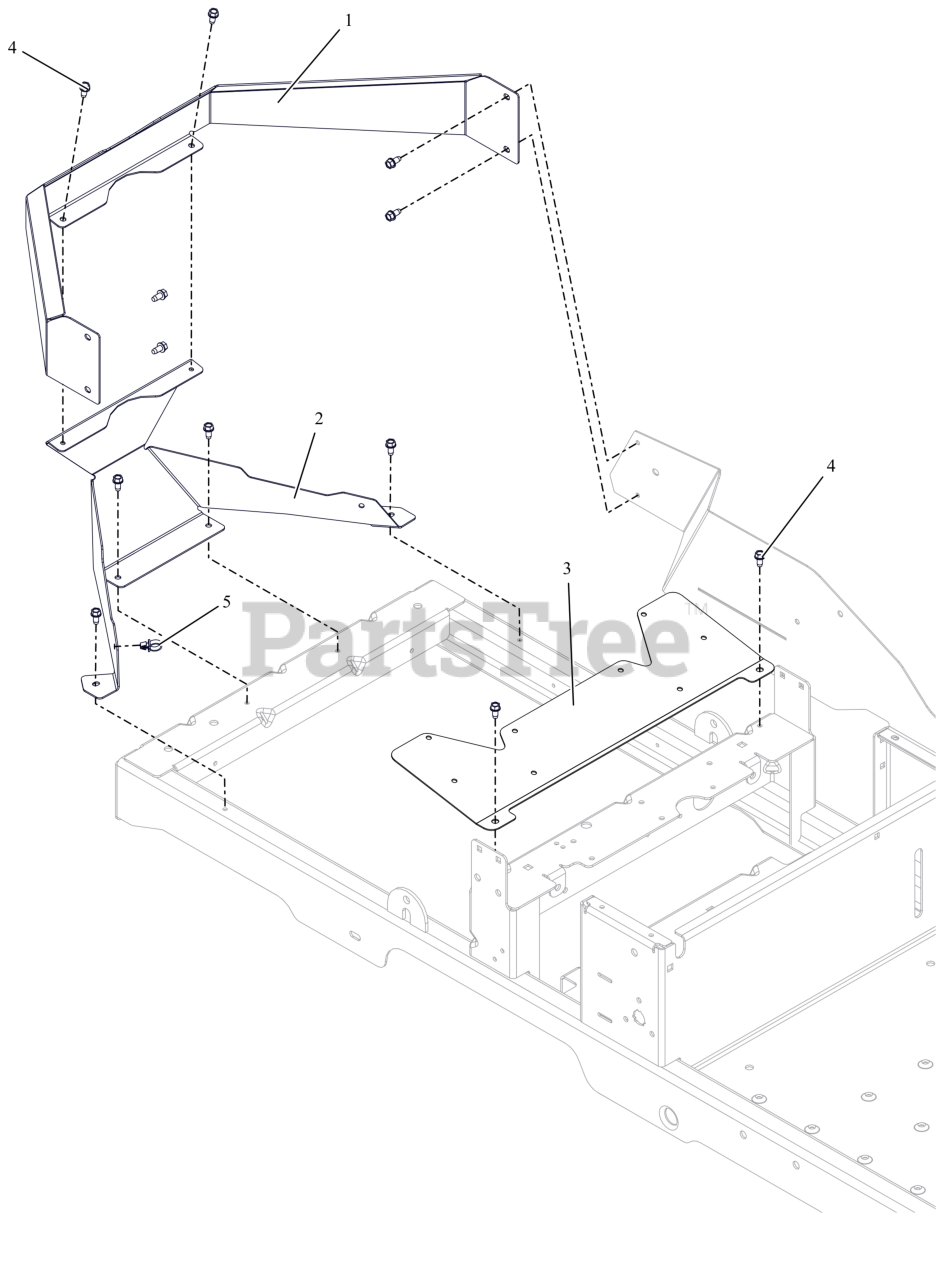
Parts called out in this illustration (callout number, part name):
1	WRAP, REAR (ORANGE)
2	WRAP, REAR
3	KIT, FAN GUARD W/DECAL
4	SCR-TAP .25-20X.50 HWH ZCC
5	ROUTING CLIP (1/2" ID)
